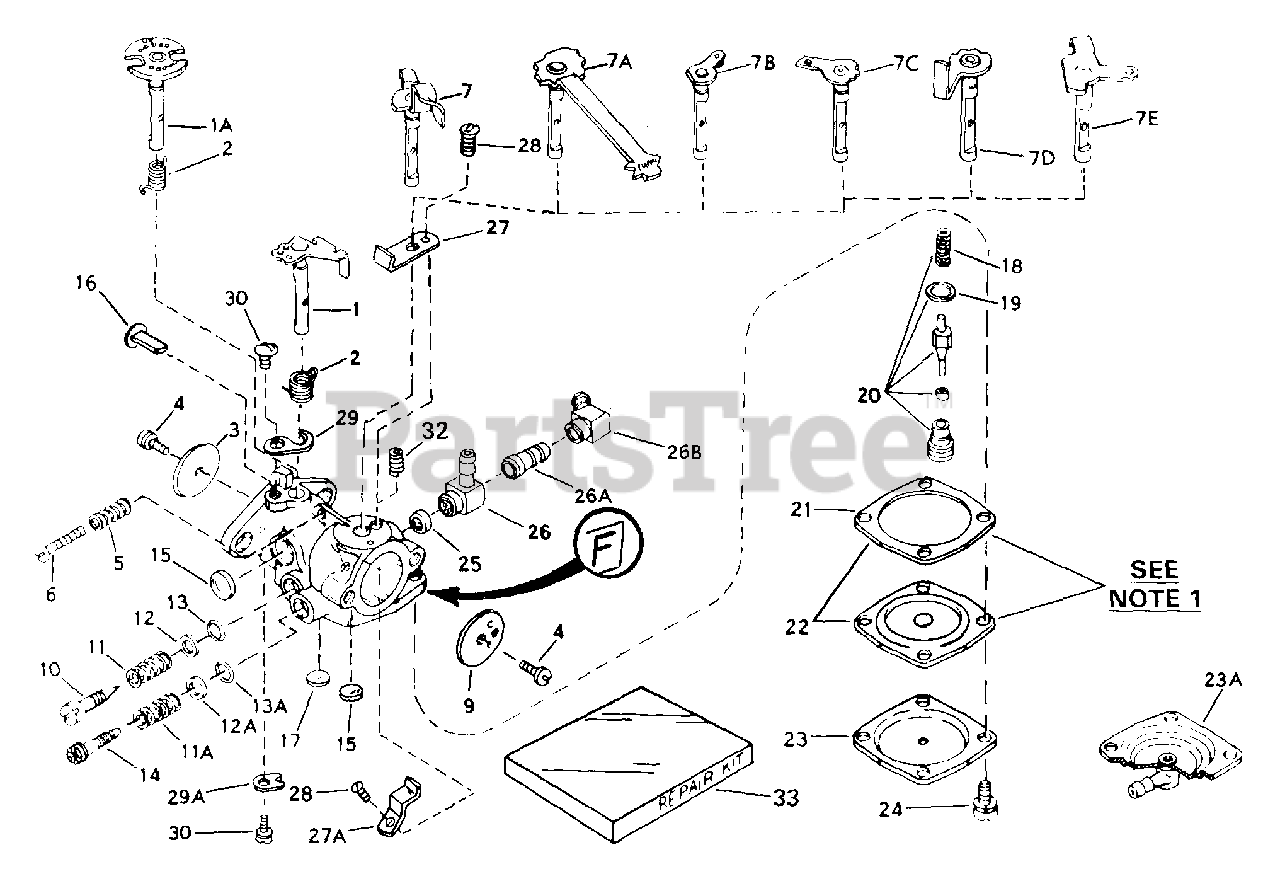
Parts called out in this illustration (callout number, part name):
1	"Shaft & Lever Assy., Throttle
2	Spring, Throttle return
3	Shutter, Throttle
4	Screw, Throttle & Choke shutter
5	Spring, Idle speed
6	Screw, Idle regulating
7C	Shaft & Lever Assy., Choke
9	Shutter, Choke
10	Screw, Idle adj.
11	Spring, Idle adj. screw
11A	Spring, Main adj. screw
12	Spring, Idle adj. screw
12A	Spring, Main adj. screw
13	"O" Ring, Idle adj. screw
13A	"O" Ring, Main adj. screw
14	Screw, Main adj. (.0225 dia. hole)
15	Plug, Welch
16	Element, Pump
17	Plug, Welch
18	Spring, Valve
19	Gasket, Valve seat
20	Inlet Needle, Seat, Spring & Gasket A ssy.
21	Gasket, Diaphragm
22	Diaphragm Assy.
23	Cover, Diaphragm
24	Screw, Diaphragm cover
25	Valve, Check
26	Fitting, Fuel inlet
27	Spring, Detent
28	Screw, Detent
29	Retainer, Throttle shaft
30	Screw, Retainer
33	Repair Kit
